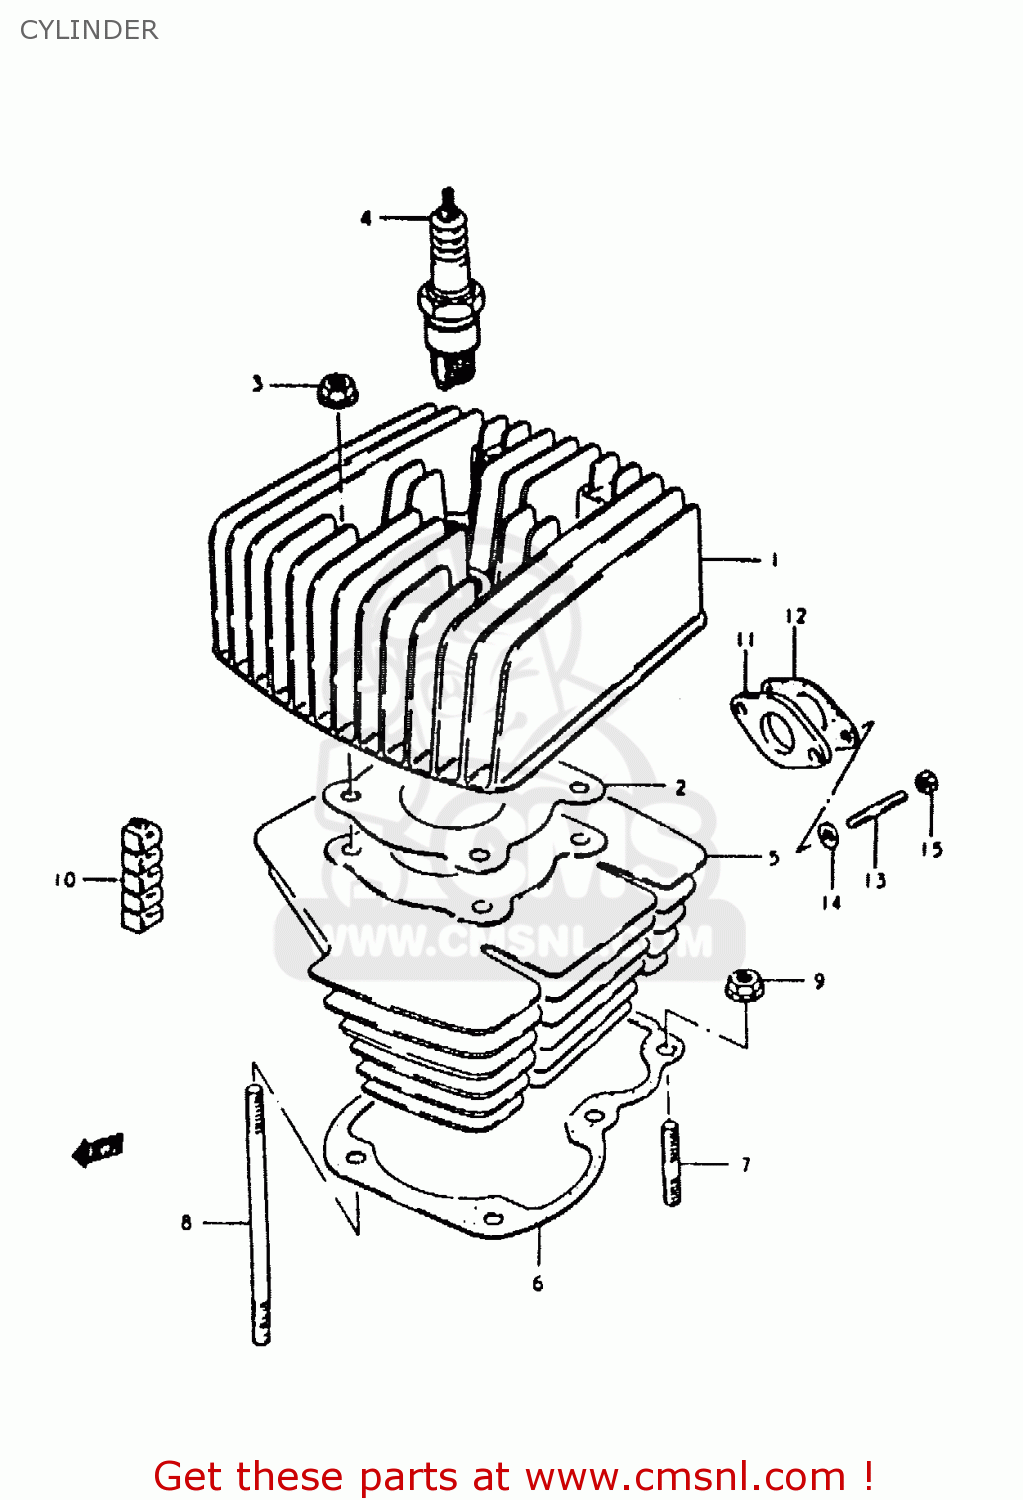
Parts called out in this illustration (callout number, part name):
1	CYLINDER HEAD
2	GASKET,CYLINDER HEAD (NAS)
3	NUT
4	SPARK PLUG (ND,W20EP)
5	CYLINDER
6	GASKET,CYLINDER (MCA)
7	BOLT,STUD
8	STUD 6X16
9	NUT
10	PAD,CYLINDER
11	INSULATOR,CARBURETOR
12	GASKET,CARBURETOR (MCA)
13	STUD BOLT
14	WASHER
15	NUT
